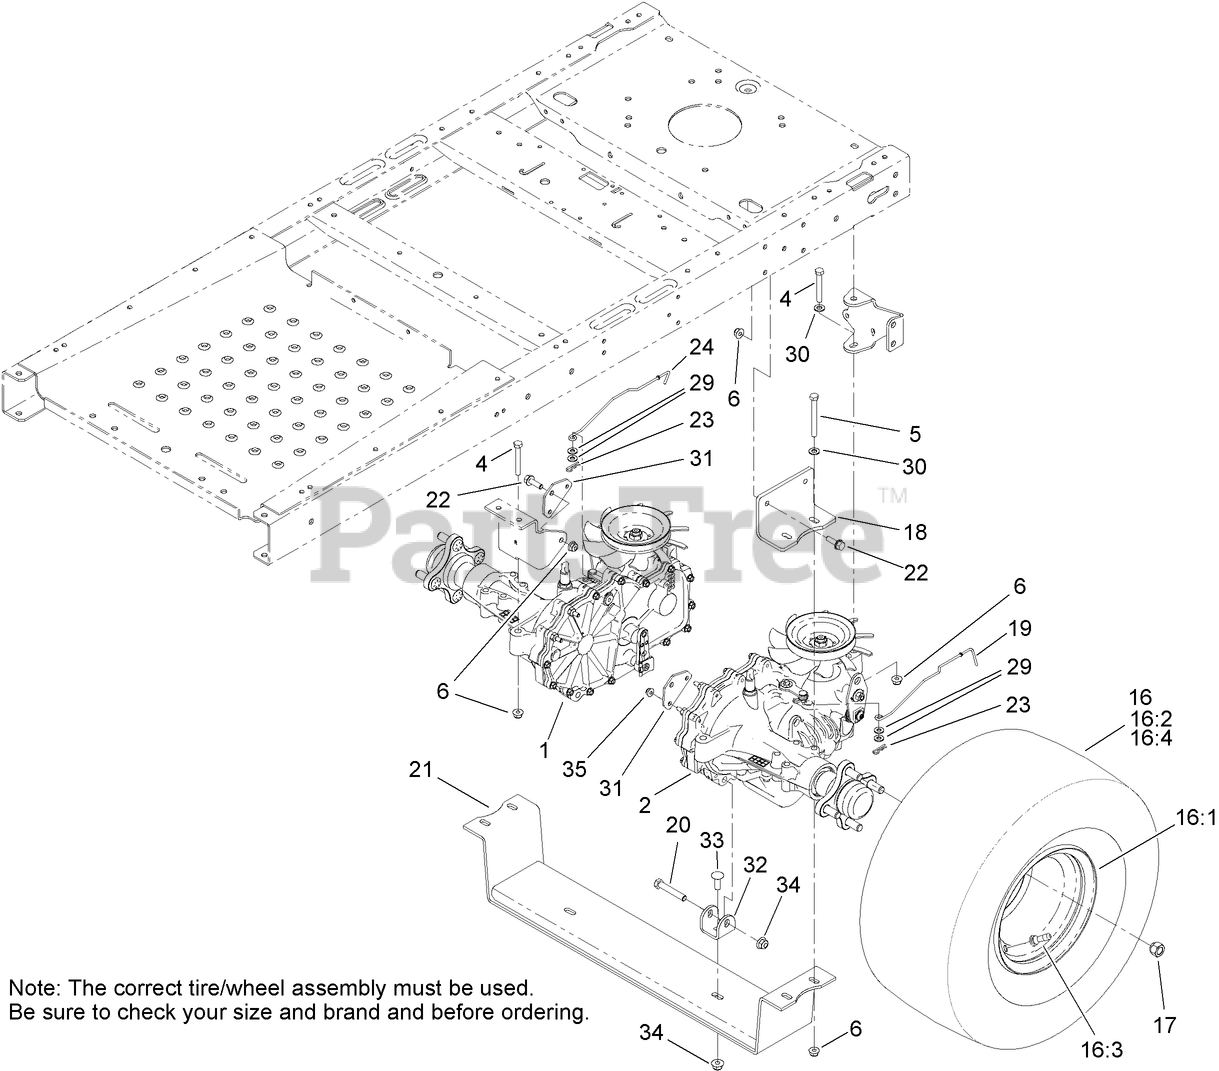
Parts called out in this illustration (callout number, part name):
1	RH HYDRO TRANSAXLE ASM
2	LH HYDRO TRANSAXLE ASM
4	SCREW-HH
5	SCREW-HH
6	NUT-HF, NI
16	4 PLY WHEEL AND TIRE ASM
16	Wheel and Tire ASM (K-500)
16	SEE NOTE
16:2	TIRE-4 PLY
16:4	TUBE-INNER
17	NUT-LUG
18	MOUNT-HYDRO
19	ROD-BYPASS, LH
20	SCREW-HH
21	MOUNT-HYDRO
22	SCREW-HHF
24	ROD-BYPASS, RH
29	WASHER-FLAT
30	WASHER-PLAIN
31	PLATE-HYDRO MOUNT
32	TAB-HYDRO
33	SCREW-CARR
34	NUT-HF, NI
35	NUT-HF
